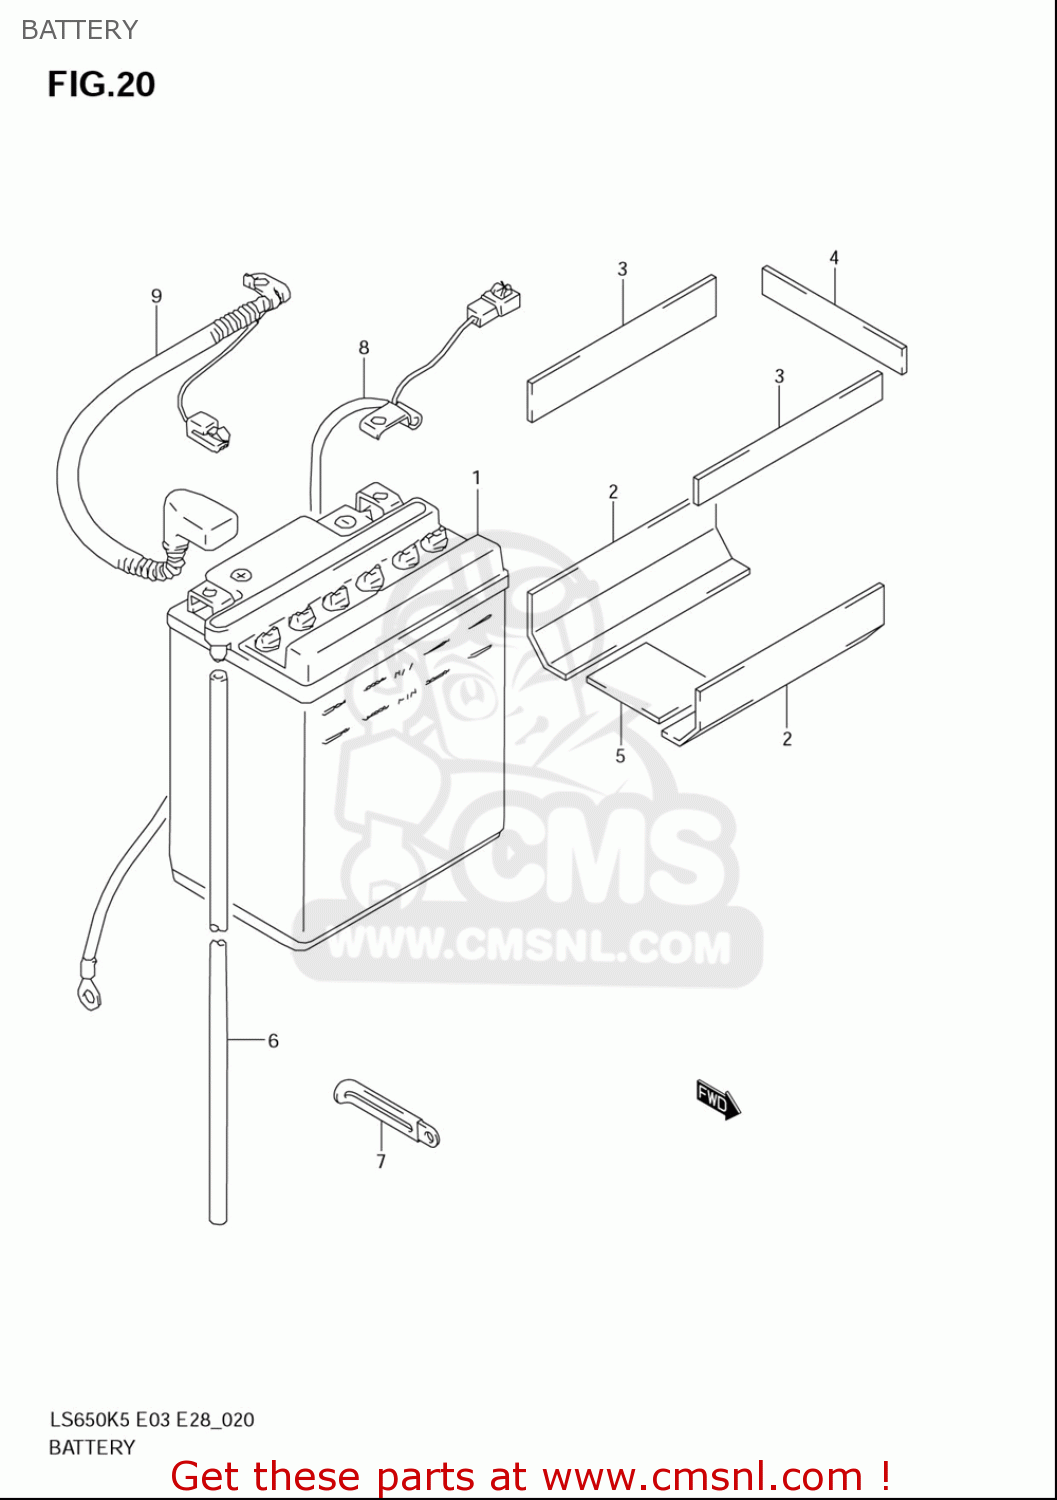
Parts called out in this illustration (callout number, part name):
1	BATTERY(YB14L-B2,12V14.7AH)
2	PROTECTOR(170X95X3.0)
4	PROTECTOR(80X80X2)
5	PROTECTOR(50X50X5)
6	HOSE,BATTERY EXHAUST(L:780)
7	CLAMP(L:65)
8	WIRE,BATTERY MINUS
9	WIRE,BATTERY PLUS LEAD
